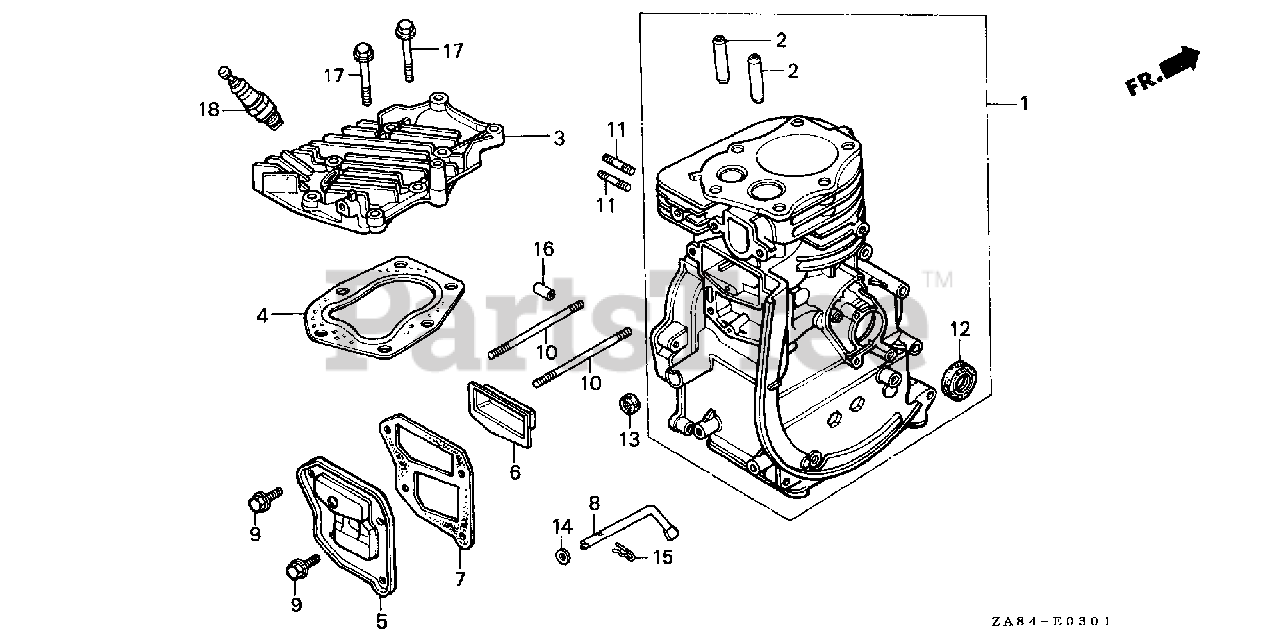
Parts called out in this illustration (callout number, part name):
1	CYLINDER ASSY.
2	GUIDE, VALVE (OS)
3	CYLINDER HEAD
4	GASKET, CYLINDER HEAD
5	COVER, TAPPET ROOM
6	SEPARATOR (INNER)
7	GASKET, TAPPET COVER
8	SHAFT, GOVERNOR ARM
9	BOLT, FLANGE (5X10)
10	BOLT, STUD (5X80)
11	BOLT, STUD (6X28)
12	OIL SEAL (17X30X6) (NOK)
14	WASHER, PLAIN (5MM)
15	PIN, LOCK (8MM)
16	PIN A, DOWEL (8X14)
17	BOLT, FLANGE (6X35)
18	SPARK PLUG (BPMR4A) (NGK)
